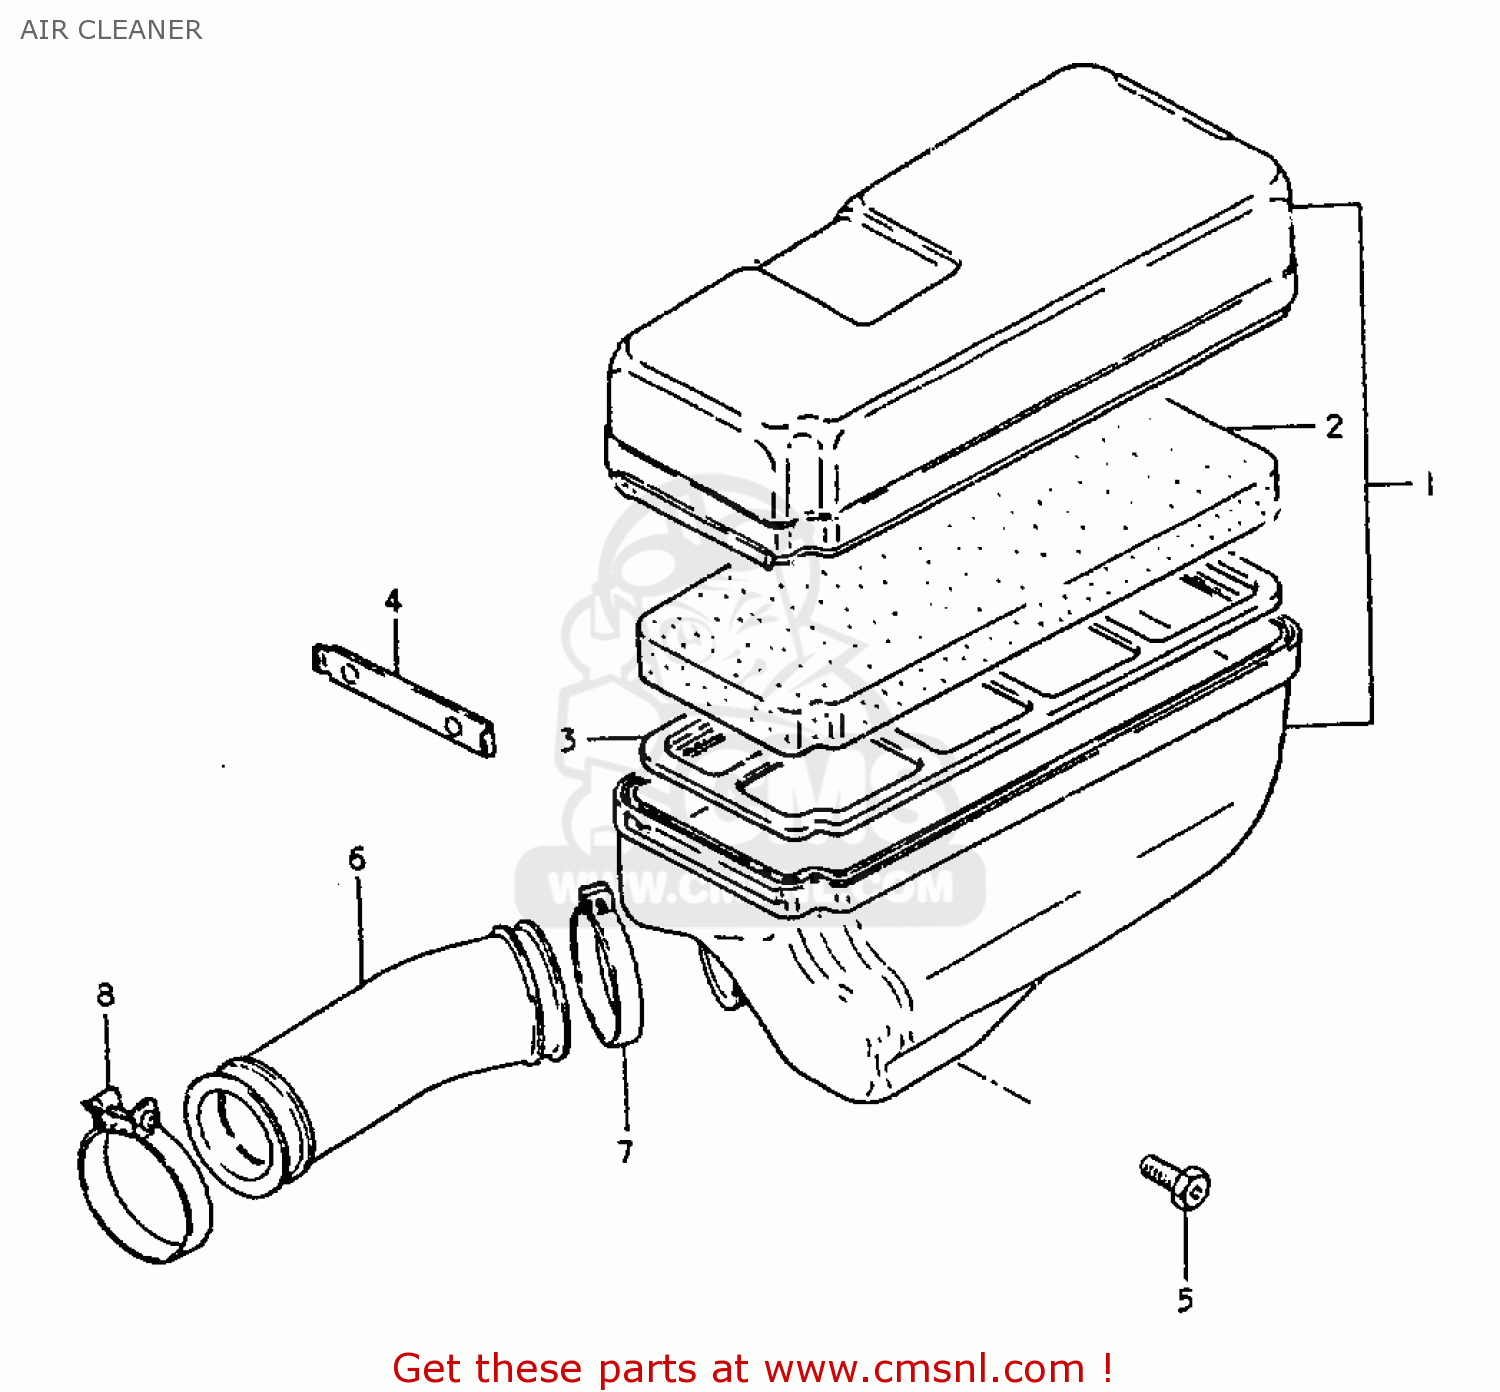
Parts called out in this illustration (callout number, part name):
1	CLEANER ASSY,A
2	FILTER
3	HOLDER
4	SLIDER
5	SCREW
6	TUBE,AIR CLEANER OUTLET
7	CLAMP
8	CLAMP
